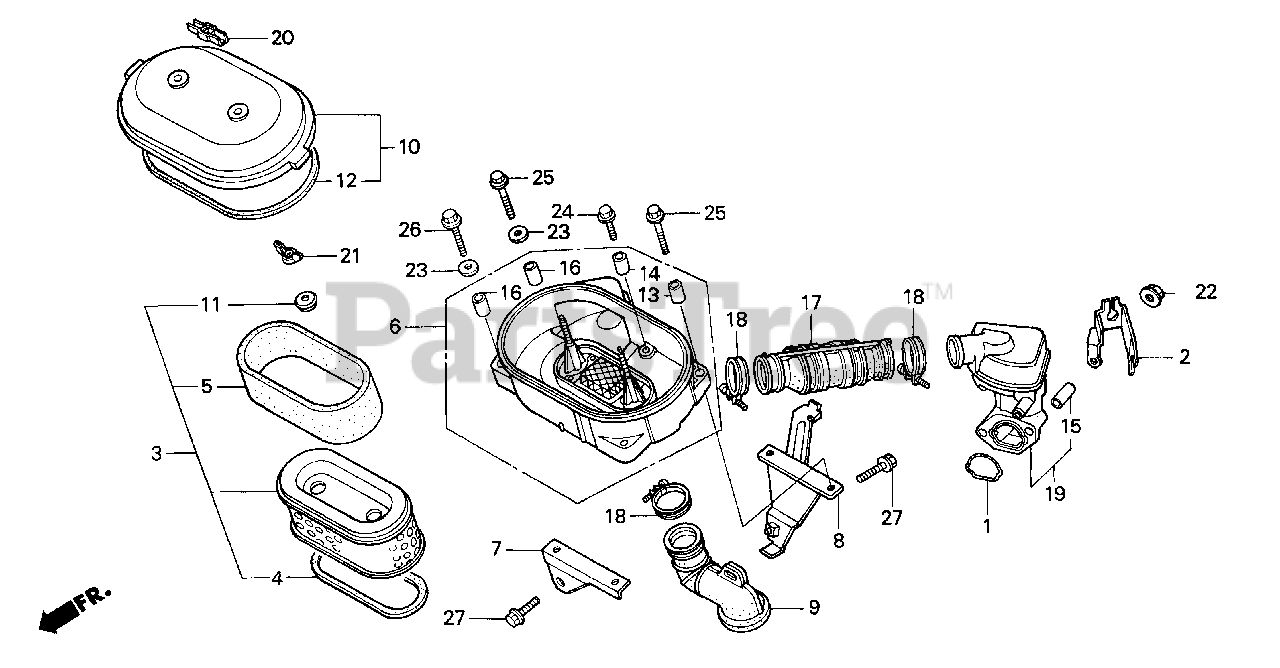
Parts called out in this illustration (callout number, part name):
1	O-RING, AIR CLEANER
2	HOLDER, CHOKE CABLE
3	ELEMENT, AIR CLEANER
5	FILTER (OUTER)
6	HOUSING, AIR CLEANER
7	STAY, AIR CLEANER (A)
8	STAY, AIR CLEANER (B)
9	GUIDE, AIR IN.
10	COVER, AIR CLEANER
11	GROMMET, AIR CLEANER
12	GASKET, AIR CLEANER COVER
13	COLLAR C, AIR CLEANER
14	COLLAR A, AIR CLEANER
15	COLLAR, AIR CLEANER
16	COLLAR B, AIR CLEANER
17	TUBE, AIR CLEANER CONNECTING
18	BAND B, CONNECTING TUBE
18	BAND B, AIR CLEANER
19	ELBOW, AIR CLEANER
20	NUT, AIR CLEANER COVER (DACRO COATING)
21	NUT, TOOL BOX SETTING
22	NUT, FLANGE (6MM)
23	WASHER, PLAIN (6MM)
24	BOLT, FLANGE (6X16)
25	BOLT, FLANGE (6X28)
26	BOLT, FLANGE (6X32)
27	BOLT, FLANGE (8X25)
